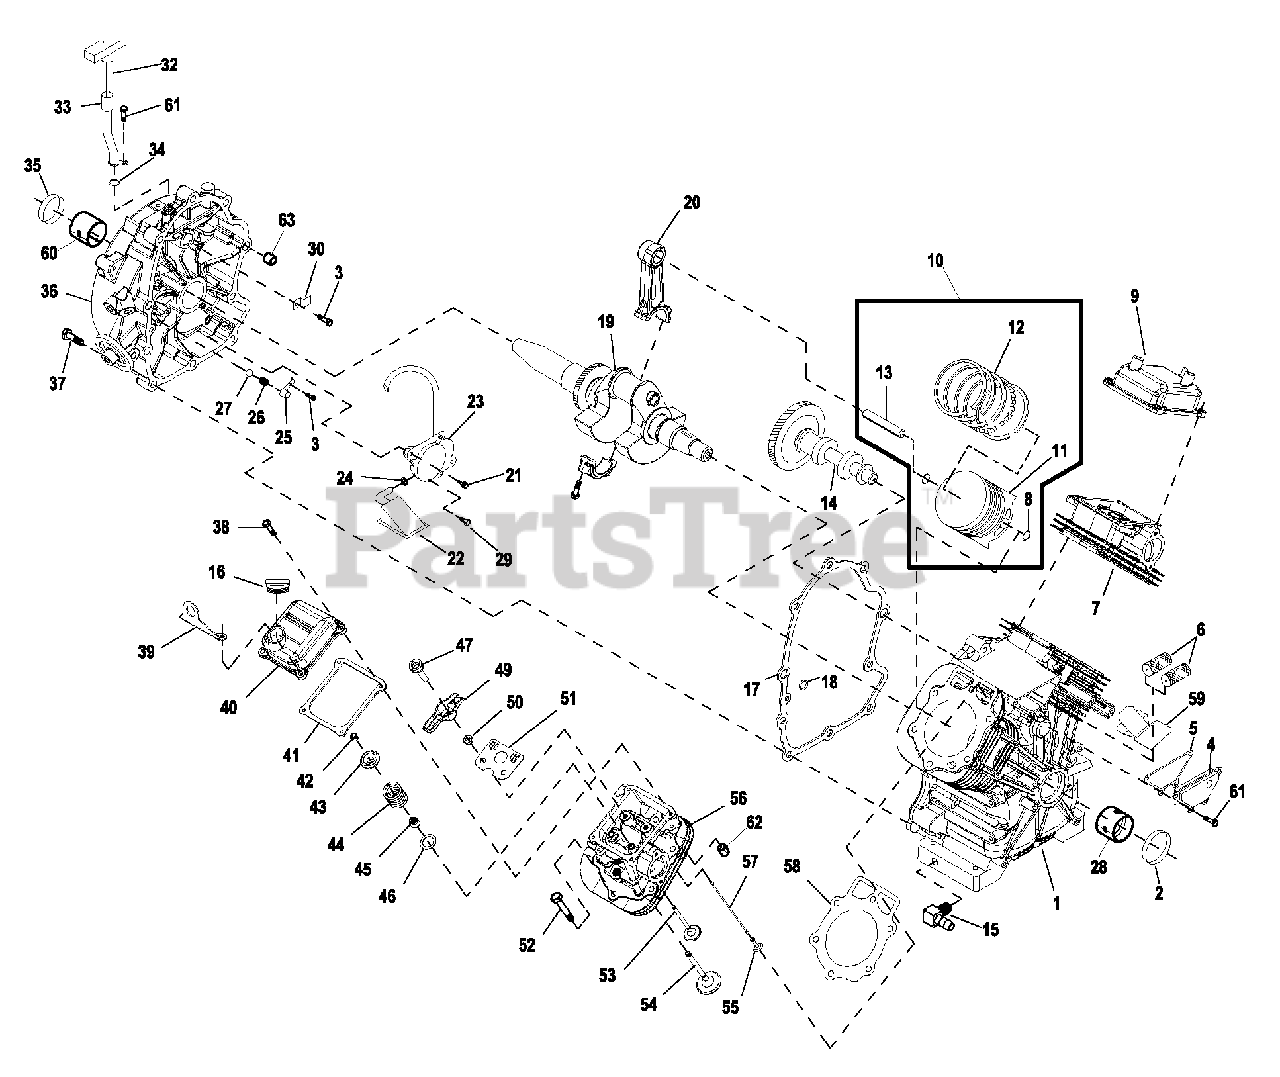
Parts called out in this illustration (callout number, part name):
1	CCASE ASM DUAL DRAIN W/PLUGS
2	SEAL CSHFT FLYWL SIDE RED
3	SCREW, HHFCS M6-1.0 X 12 G8.8
4	ASSEMBLY, BREATHER DUAL VALVE
5	GASKET, BREATHER COVER
6	SEPARATOR, OIL BREATHER
7	ASSY HEAD CYL #1 GT-999 20KW
8	RETAINER, PISTON PIN 20
9	ASSY, ROCKER COVER W/BARB
10	ASSY PISTON DISH TOP GT999
11	PISTON DISH TOP 90 HSB 2013
12	RING SET, PISTON TOP DIA 90
13	WRIST PIN 999 20X13X48 LONG
14	ASSEMBLY, CAMSHAFT & GEAR
15	BARBED ELBOW, 90 DEG. 3/8NPT X 3/8 VS
16	ASSEMBLY, OIL FILL CAP
17	GASKET, CRANK CASE
18	SEAL, OIL PASSAGE
19	CRANKSHAFT AND GEAR GTH-990
20	ASSY CONROD MACH GT990
21	SCREW SHC SEMS M6-1.0 X 50 G8.8
22	SCREEN, OIL PICKUP
23	ASSY,OIL PUMP GTH W/O O-RING
24	O-RING, 0.49 ID X 0.07 THICK
25	COVER, OIL RELIEF
26	SPRING, OIL RELIEF
27	BALL, 1/2D OIL RELIEF
28	SLEEVE,BEARING,CCASE
29	SCREW, PLASTITE HI-LOW #10
30	CLAMP, OIL TUBE
32	ASSEMBLY, DIPSTICK GTH-990 PORTABLE
33	TUBE, DIPSTICK
34	O-RING, 3/8 X 1/2
35	SEAL CSHFT PTO 760/990 RED
36	GEARCOVER / ADAPTOR GTH990/760
37	SCREW, HHFC M10-1.5 X 55
38	SCREW HHFC M6-1.0 X 25
39	LIFT HOOK
40	COVER, ROCKER W/OIL FILL "GENERAC" TEXT
41	GASKET, VALVE COVER
42	KEEPER, VALVE SPRING
43	RETAINER, VALVE SPRING
44	SPRING, VALVE
45	SEAL, VALVE STEM D7
46	WASHER, VALVE SPRING
47	STUD, ROCKER ARM PIVOT
49	ROCKER ARM
50	NUT, HEX M8-1.0 GB YELLOW CHROM
51	PUSH ROD GUIDE PLATE
52	SCREW HHFC M8-1.25 X 65
53	VALVE, EXHAUST
54	VALVE, INTAKE
55	TAPPET, SOLID
56	ASSY HEAD CYL #2 GT-999 20KW
57	PUSHROD 147
58	GASKET, HEAD
59	DIVERTER, BREATHER GTH
60	SLEEVE PTO BEARING GTH990
61	SCREW HHFCS M6-1.0 X 10
62	SLEEVE DOWEL PIN 12 DIA.
63	SLEEVE DOWEL PIN DIA.14
64	PLUG STD PIPE 3/8 STEEL SQ HD
